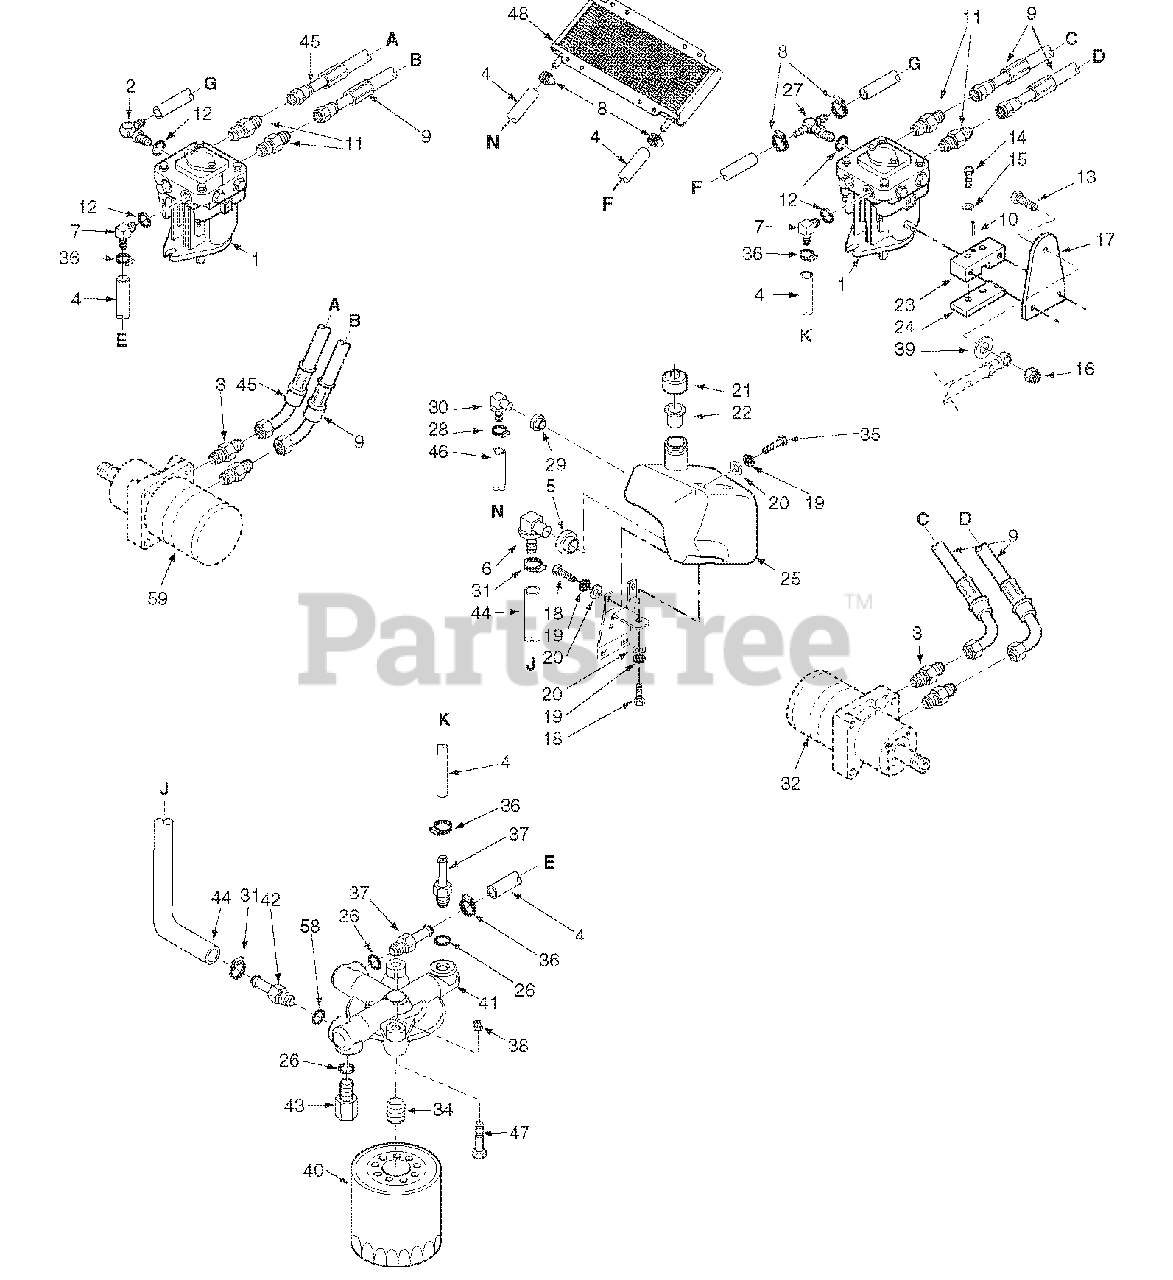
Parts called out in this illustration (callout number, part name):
1	Pump, BDP-10A-316 (LH)
2	Elbow, 90 Degree 9/16" O-Ring x 3/8" Hose
3	Fitting, 1/2" JIC x 5/8" O-Ring
4	Hose, 3/8" Pushlock
5	Bushing
6	Fitting
7	Elbow, 90 Degree 9/16" O-Ring x 3/8" Hose
8	Hose Clamp, .69" Dia.
9	Hose Assembly
10	Roll Pin
11	Fitting, 1/2" JIC x 1/2" O-Ring
12	O-Ring
13	Bolt, Hex Head 3/8-16 x 1-1/2"
14	Bolt, Hex Head 1/4-20 x 1-1/4"
15	Lockwasher
16	Nut, Elastic Stop 3/8-16
17	Control Lever
18	Bolt, Hex Head 5/16-18 x 3/4"
19	Lockwasher, 5/16"
20	Flatwasher, 5/16-.375 x .875 x .083
21	Cap, Hydraulic Tank
22	Insert, Filler Neck
23	Control Block
24	Clamp Plate
25	Hydraulic Tank Assembly w/Fittings
26	O-Ring, 9/16"
27	Tee Fitting, O-Ring to Barb
28	Clamp, .69" Max. / .25" Min. Dia.
29	Bushing
30	Elbow, 0.38" Hose
32	Wheel Motor, Parker
33	O-Ring, 3/4"
34	Nipple, Oil Filter 1.0-12 UNF-2A x 1-1/4"
35	Bolt, Hex Head 5/16-18 x 1-1/2"
36	Clamp, .69" Max. / .25" Min. Dia.
37	Fitting, 9/16" O-Ring x 3/8" Hose
38	Nut, Serr. Flange 5/16-18
39	Flatwasher, 3/8-.391 x .938 x .105"
40	Oil Filter
41	Filter Head Assembly
42	Fitting, 3/4" O-Ring x 3/8" Hose
43	Plug, 9/16-18 O-Ring
44	Hose, Filter Inlet
45	Hose Assembly
46	Hose, 3/8" Pushlock 15" Long
47	Bolt, Hex Head 5/16-18 x 2"
48	Cooler, Transmission
